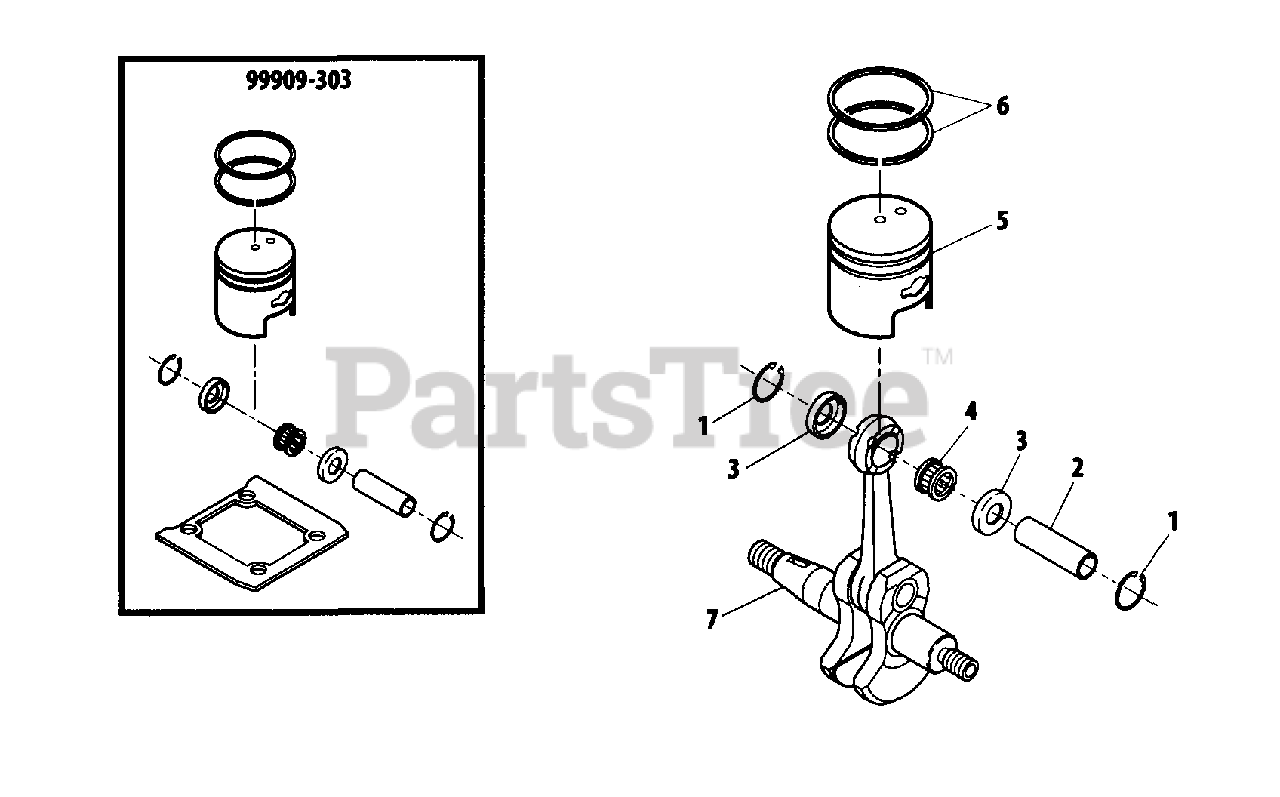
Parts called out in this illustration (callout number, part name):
1	RING, RETAINING
2	PIN, PISTON
3	WASHER
4	BEARING, NEEDLE
5	PISTON
6	PISTON RING SET
7	CRANKSHAFT ASSY
99909-303	PISTON ASSY
